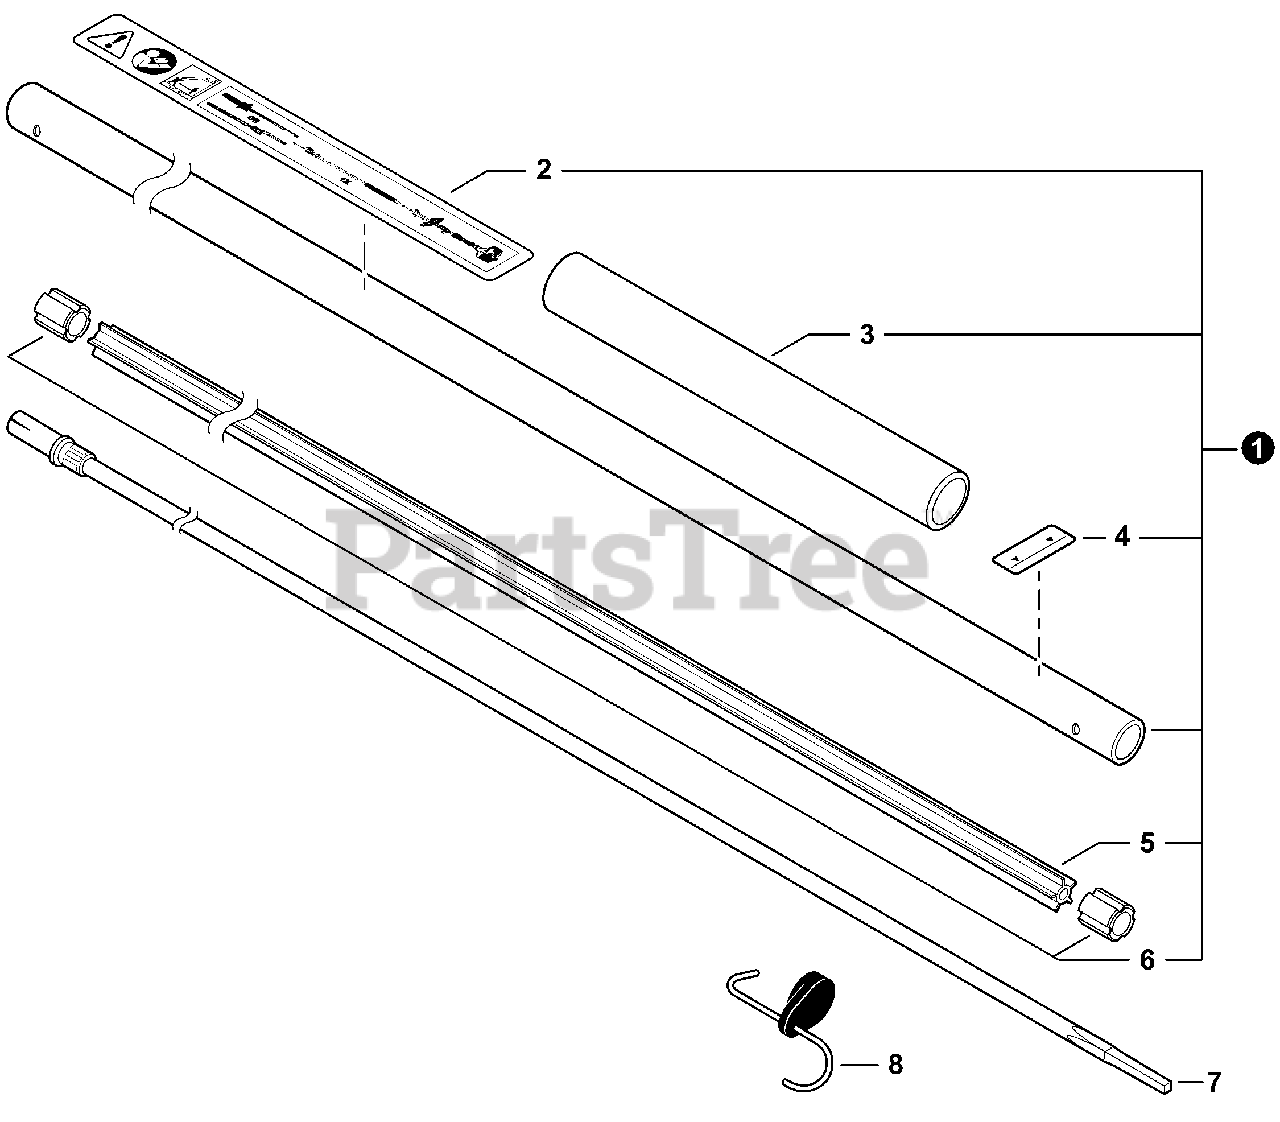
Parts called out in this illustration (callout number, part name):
1	MAIN PIPE ASSY
2	LABEL, CAUTION
3	GRIP, HANDLE
4	LABEL - ALIGNMENT
5	LINER - FLEXIBLE
7	DRIVESHAFT - FLEXIBLE
8	HANGER, ATTACHMENT
